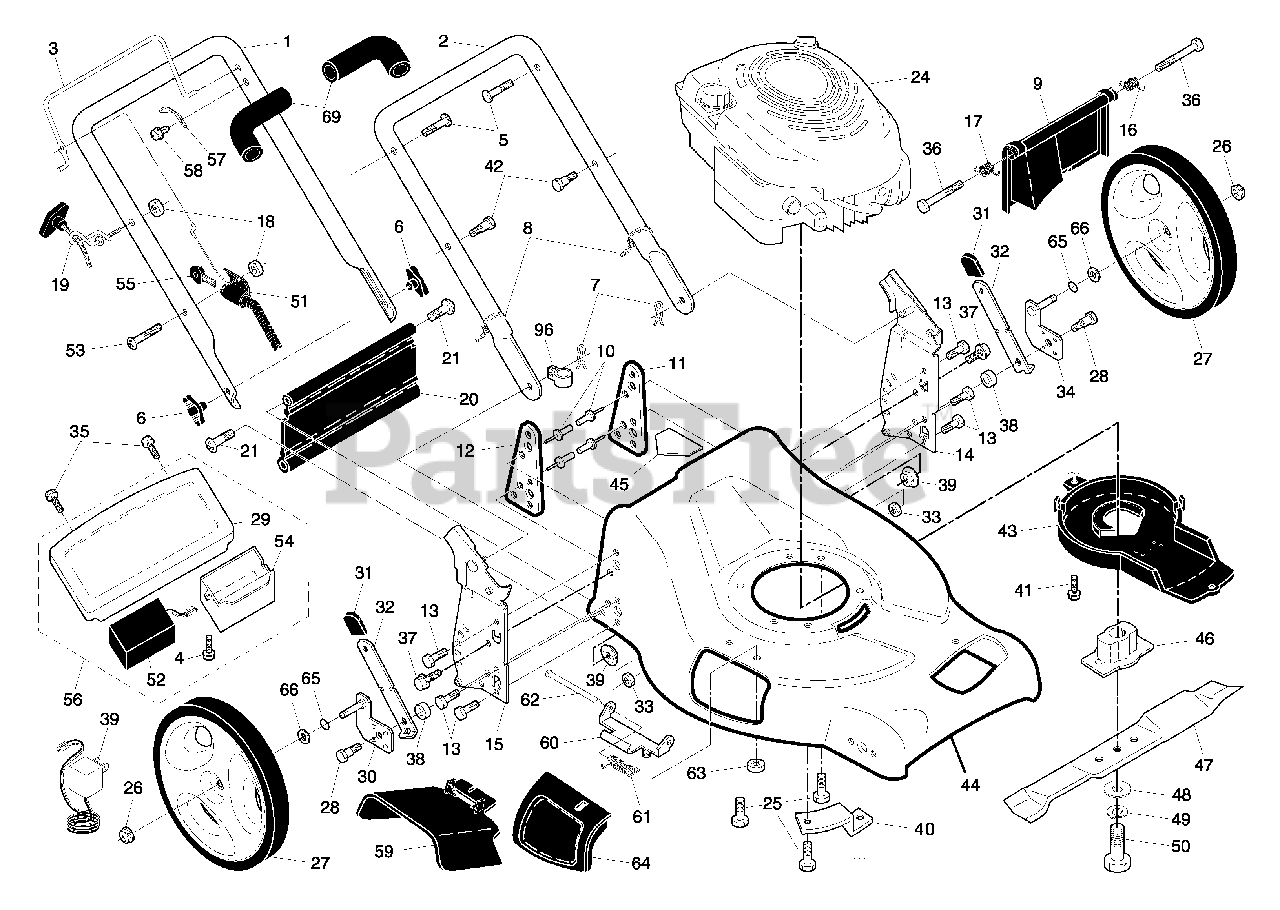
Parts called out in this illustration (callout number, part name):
1	Upper Handle
2	Lower Handle
3	Control Bar
5	Handle Bolt
6	Handle Knob
7	Hairpin Cotter
8	Wire Tie
9	Rear Door Assembly
11	Support Bracket, LH
12	Support Bracket, RH
13	Screw 1/4-20 x 5/8
14	Handle Bracket Assembly, LH
15	Handle Bracket Assembly, RH
16	Spring, Rear Door, LH
17	Spring, Rear Door, RH
18	Keps Locknut 1/4-20
19	Rope Guide
20	Rear Skirt
24	Engine, Briggs & Stratton
25	Hex Head Thread Rolling Screw 3/8-16 x 1-1/8
26	Hex Flange Nut
27	Wheel & Tire Assembly, Rear
28	Shoulder Bolt 5/16-18 x .33
29	Trim Panel
30	Axle Arm Assembly, RH
31	Selector Knob
32	Selector Spring
33	Nut, Hex 5/16-18
34	Axle Arm Assembly, LH
37	Bolt
39	Charger, Battery
40	Mounting Bracket, Debris Shield
43	Debris Shield
44	Kit, Lawn Mower Housing
45	Danger Decal
46	Blade Adapter
47	Blade, 21
48	Hardened Washer
49	Helical Washer 3/8-24 x 1-3/8 Grade 8
50	Hex Head Machine Screw 3/8-24 x 1-3/8 Grade 8
51	Key Start Switch
52	Battery
54	Battery Box
56	Trim Panel / Battery / Battery Box Assembly
57	Upstop Bracket
59	Discharge Deflector
60	Hinge Bracket
63	Nut, Hex
64	Mulcher Door
66	Washer, Flat 1/2
69	Grip, Foam
96	Clip, Cable
